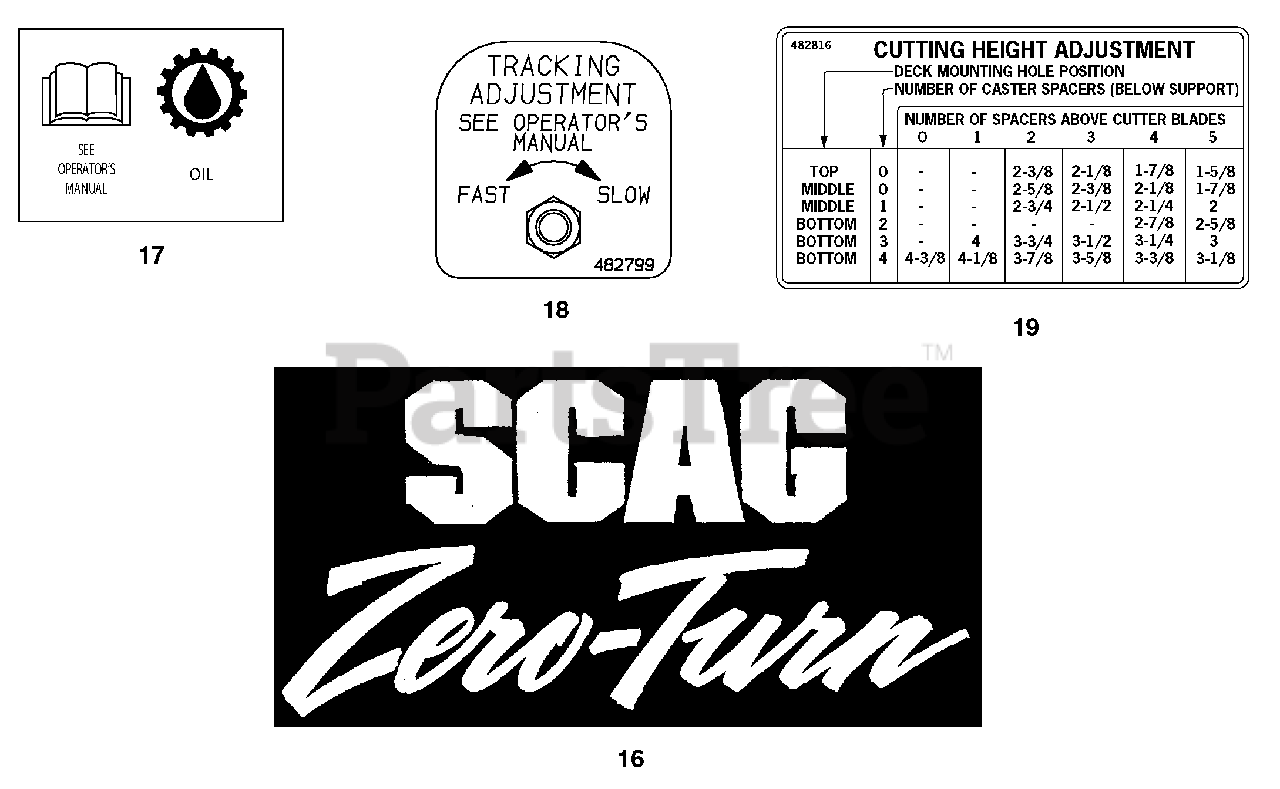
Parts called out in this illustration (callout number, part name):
16	Decal, Scag Zero Turn
17	Decal, Oil
18	Decal, Tracking Adjustment
19	Decal, Height of Cut
